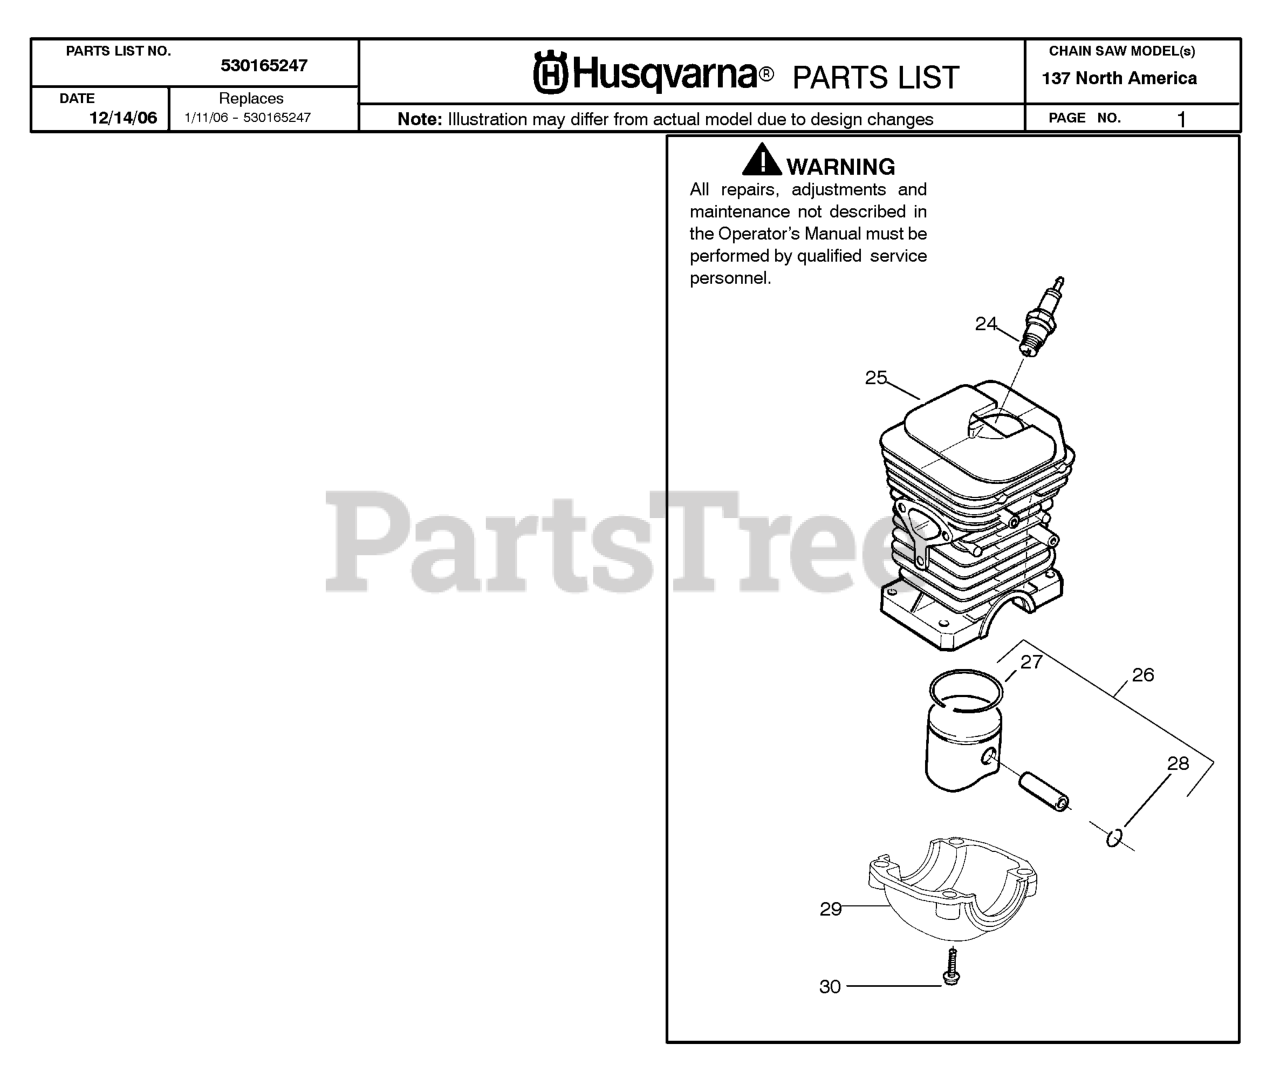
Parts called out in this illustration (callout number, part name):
24	Spark Plug (RCJ--7Y)
25	CYLINDER ASSY/136
26	PISTON KIT/136
27	PISTON RING 36
28	C-CLIP,PSTN PIN 36/41
29	CAP-CRANKSHAFT
30	SCREW-M5-0.8 X 25MM(TAP)
530031135	SCRENCH
